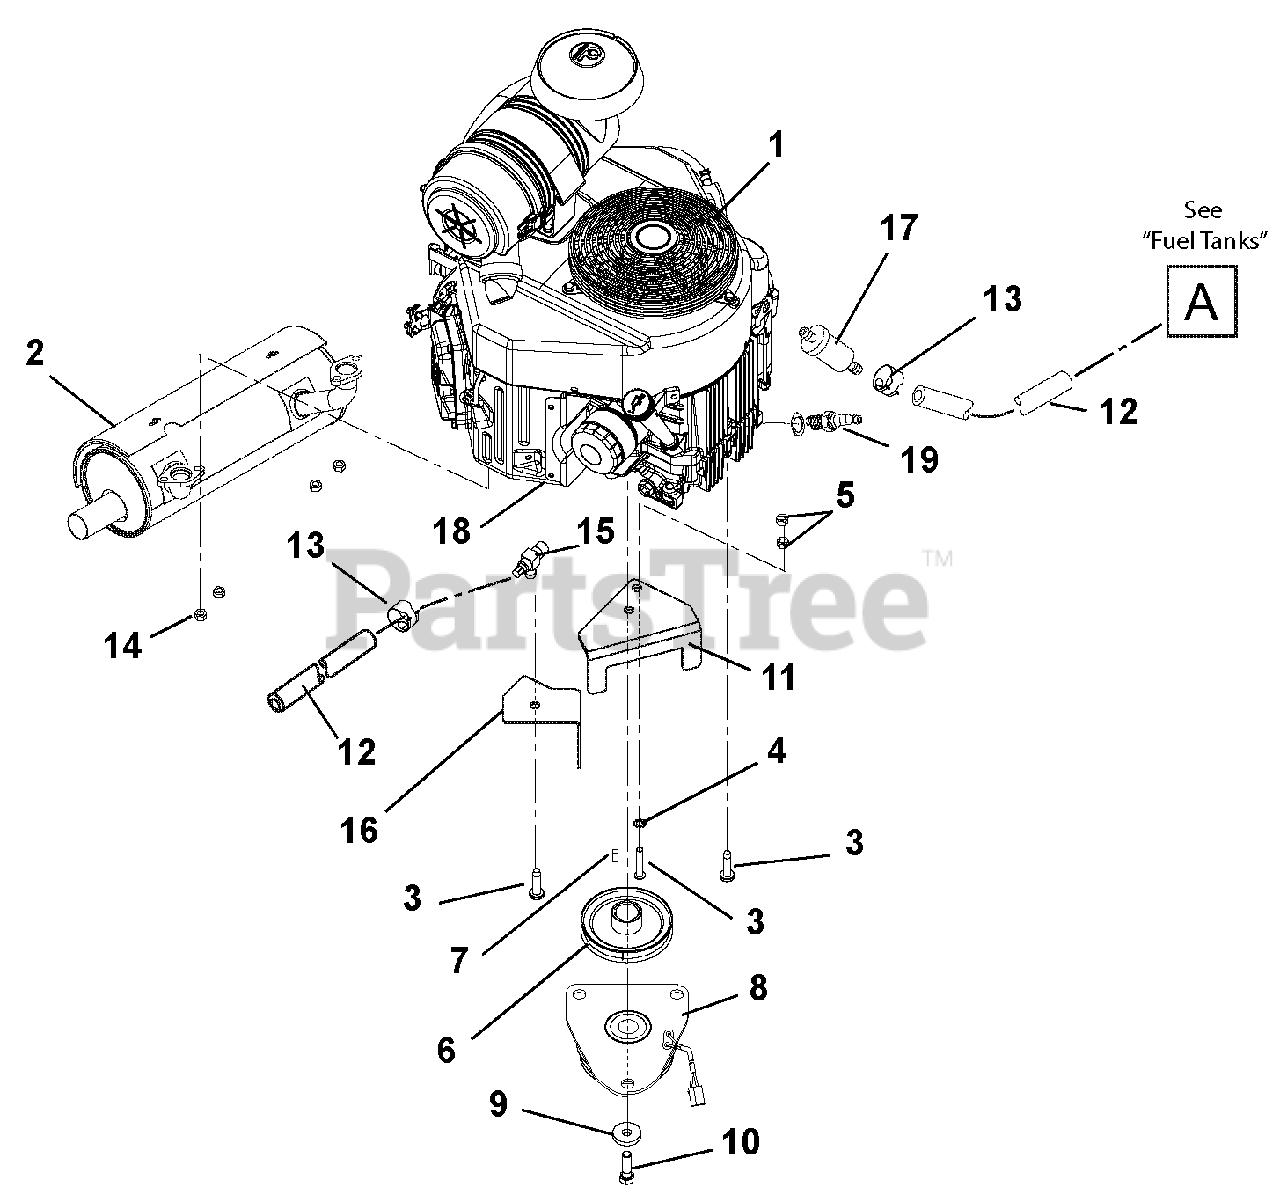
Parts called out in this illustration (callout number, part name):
1	Engine, Kawasaki FX600
2	Muffler, Kawasaki
3	Bolt, Hex .38-16 x 1.25 FTH Grade 5 EP80
4	Washer, Locking-EXT.326 x .599 x .031
5	Nut, Locking-Center .31-18
6	Pulley, 4.50 OD x 1.127 Engine
7	Key, Square .25 x .625 x .25 SAE 8630 OR SAE 1035
8	Clutch, Ogura GT1A
9	Washer, Flat-Steel .469 x 2.00 x .25
10	Bolt, Hex .44-20 x 2.00 Grade 5 EP80
11	Anchor, Ogura Clutch
12	Hose, Gas Line Low-PERM
13	Clamp, Fuel Line
14	Nut, Top Lock M8-1.25
15	Drain, .50 Oil
16	Guard, Clutch Wire
17	Fuel Filter, Kawasaki
18	Oil Filter, Kawasaki
19	Spark Plug, Kawasaki
20	Air Filter, Kawasaki
21	Pre-Filter
